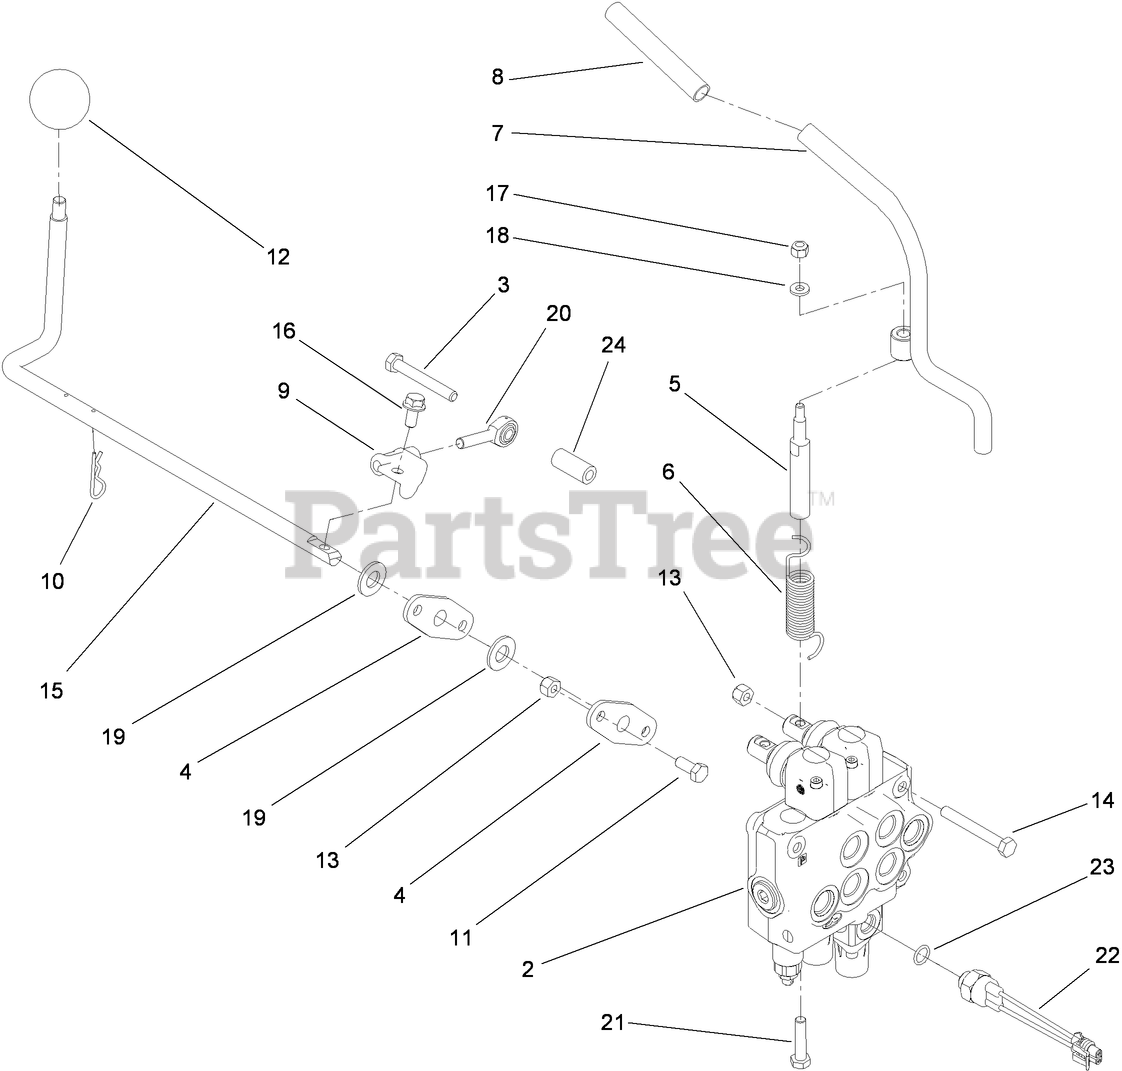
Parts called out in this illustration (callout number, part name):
2	HYD VALVE ASM
3	SCREW-HH
4	BEARING-WHEEL, FRICTION
5	SPACER-HIFLO
6	SPRING-TORSION
7	LEVER-AUXILIARY
8	GRIP-RUBBER
9	BRACKET-CONTROL
10	PIN-HAIR
11	SCREW-HH
13	NUT-LOCK, NI
14	SCREW-HH
15	ROD-LEVER, CYLINDER
16	SCREW-HHF
17	NUT-LOCK, NI
18	WASHER-FLAT
19	WASHER-FLAT
20	BEARING-ROD END
21	SCREW
22	SWITCH-BALL
23	O-RING
24	SPACER
